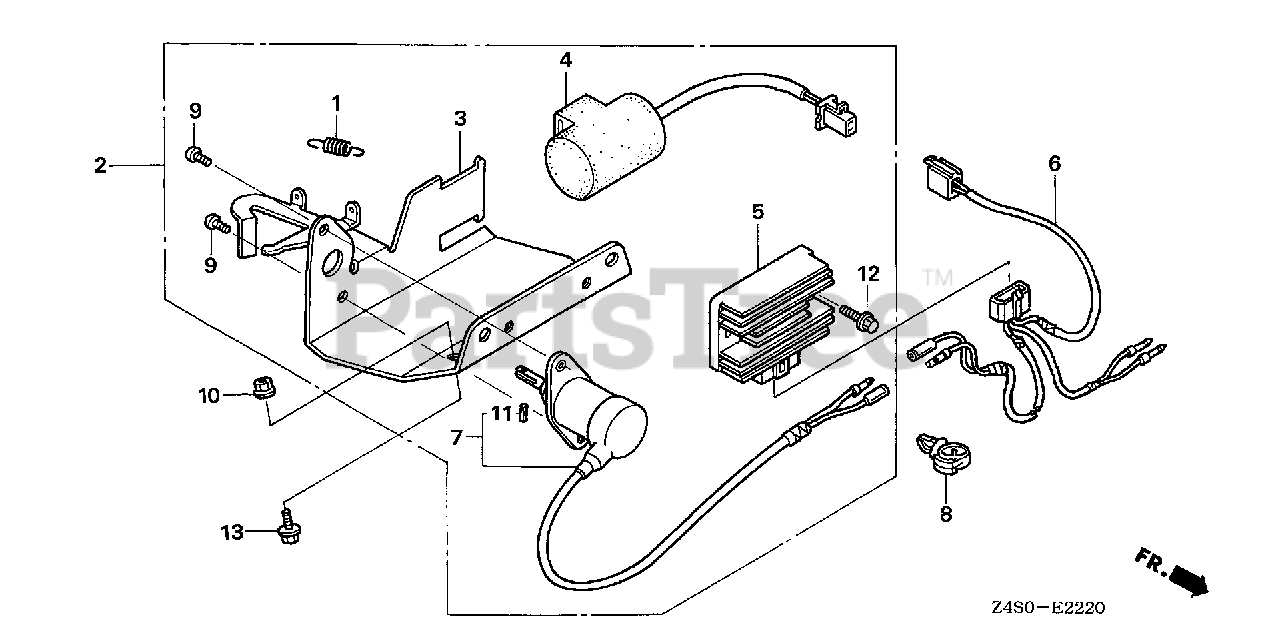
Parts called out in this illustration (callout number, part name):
1	SPRING, CHOKE RETURN
2	THROTTLE ASSY., AUTO
3	LEVER, SOLENOID THROTTLE
4	CONDENSER UNIT
5	RECTIFIER ASSY., REGULATOR
6	SUB-HARNESS ASSY.
7	SOLENOID ASSY., AUTO THROTTLE
8	CLIP, WIRE HARNESS (25MM)
9	SCREW, PAN (5X8)
10	NUT, FLANGE (6MM)
11	PIN, SPRING (2X6)
12	BOLT, FLANGE (6X16)
13	BOLT, FLANGE (6X25)
